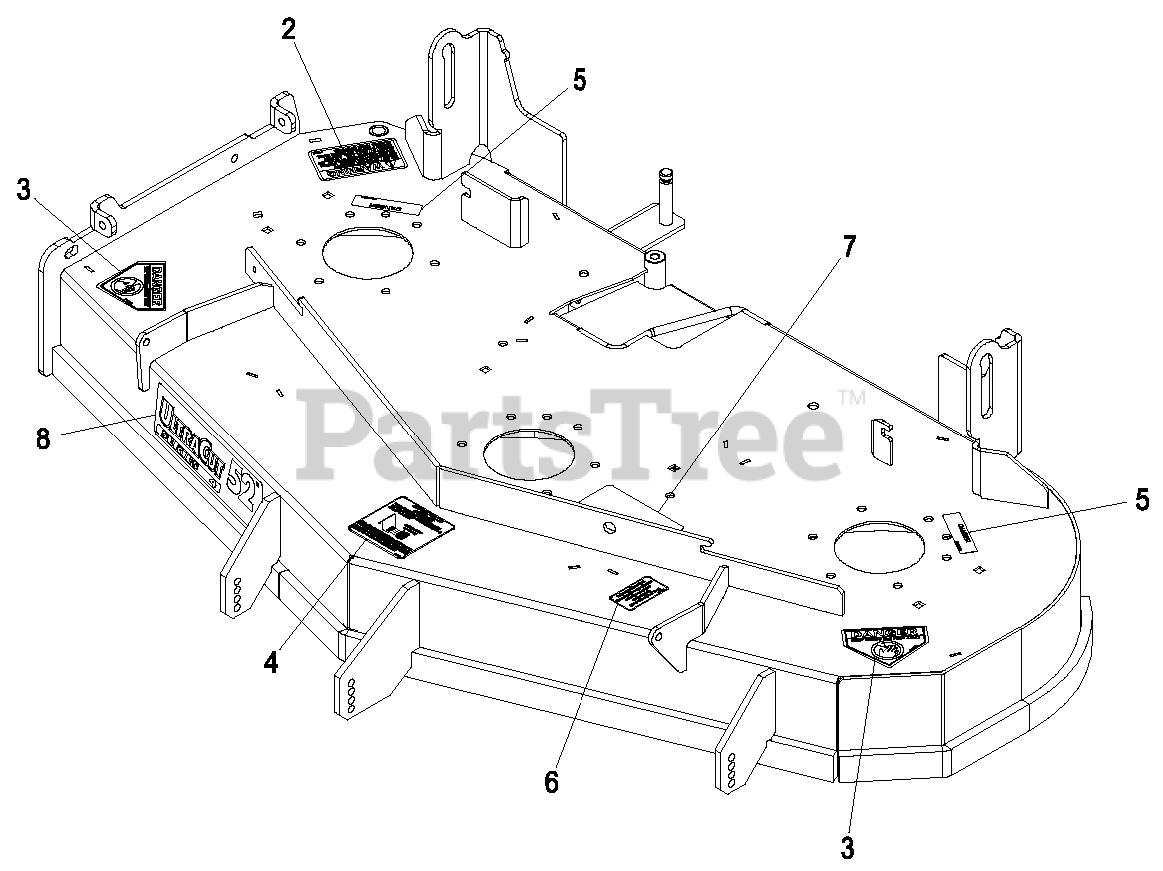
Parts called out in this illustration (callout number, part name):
2	DECAL-WARNING, DISCHARGE
3	DECAL-DANGER
4	DECAL,ANTISCALP
5	DECAL-COVER, MISSING
6	DECAL,BOLT TORQUE
7	DECAL-BELT ROUTING
8	DECAL,ULTRACUT 52 SERIES
